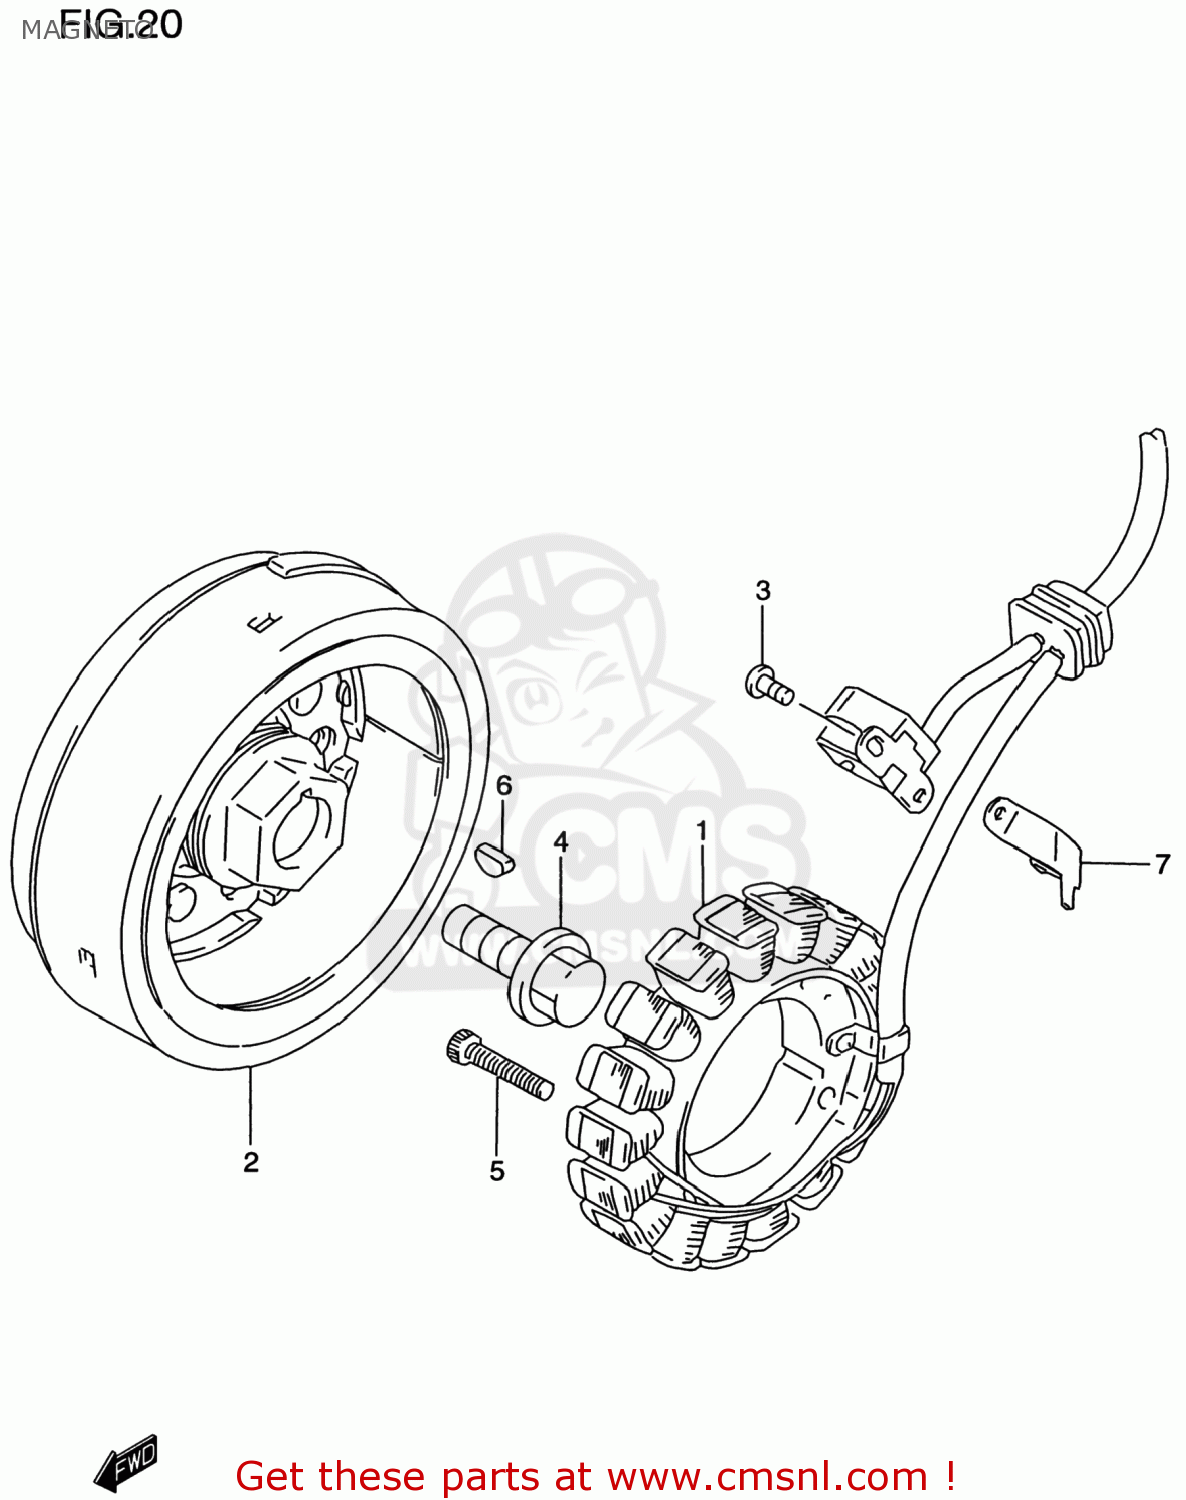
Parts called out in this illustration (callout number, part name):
1	STARTER ASSY
2	ROTOR ASSY
3	SCREW
4	BOLT(14X43)
5	BOLT
6	KEY
7	CLAMP,MAGNETO LEAD
